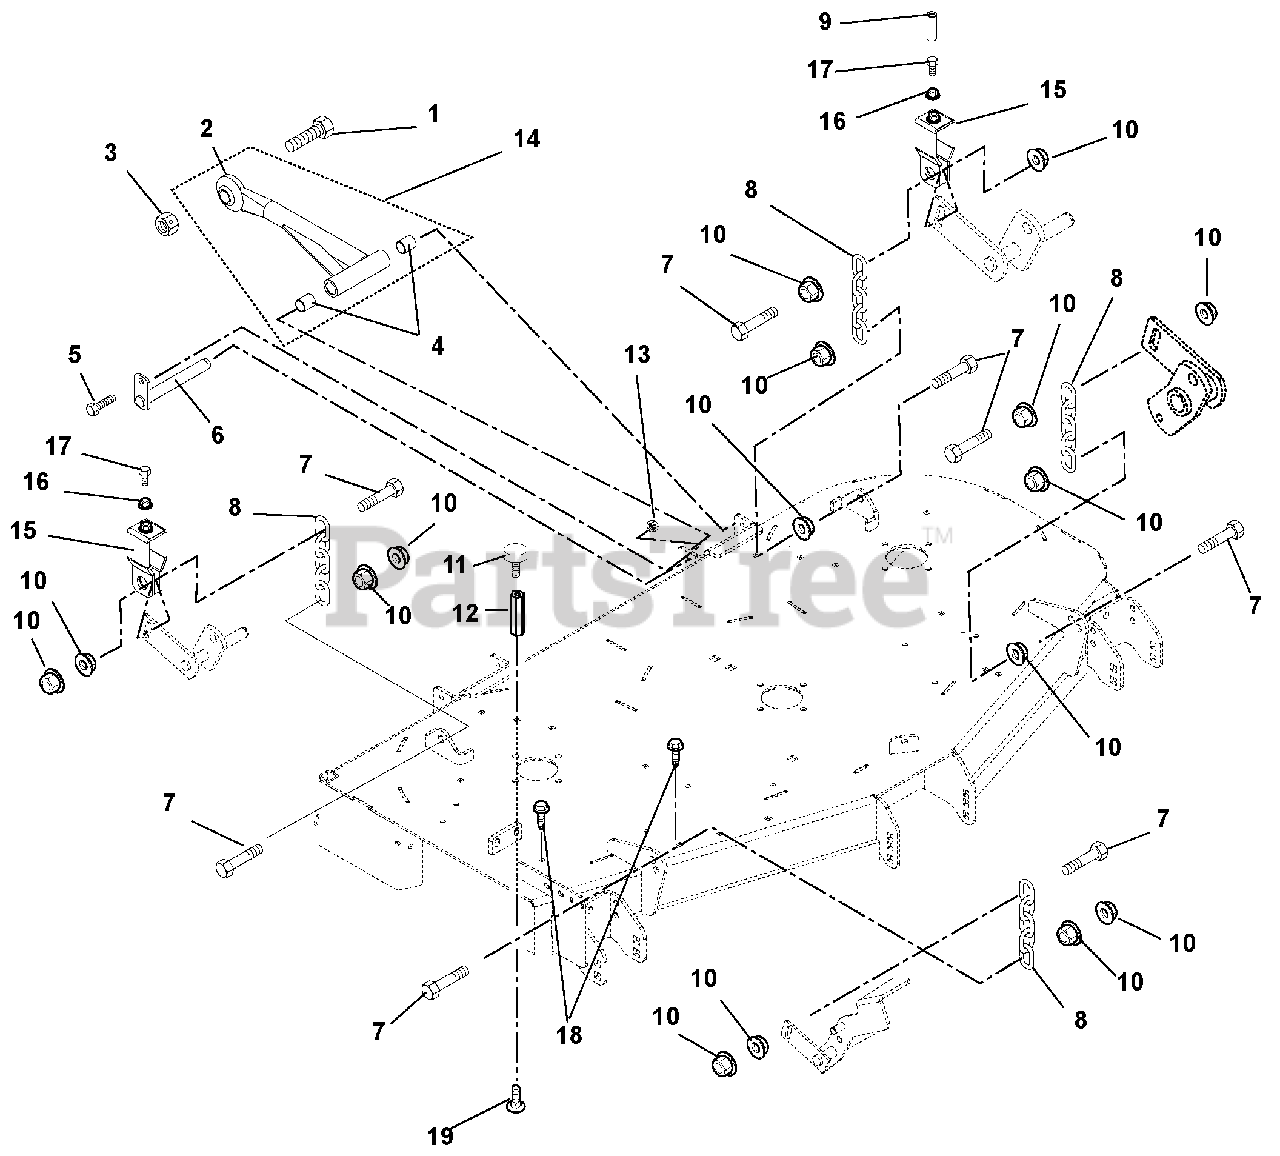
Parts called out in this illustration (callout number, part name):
1	Bolt, Hex .875-9 x 2.75 Grade 5
2	Mower Mounting Arm Weldment
3	Nut, Locking Center .875-9
4	Bearing, .75 x .875 x 1.00
5	Bolt, Hex .38-16 x 1.00 Grade 5
6	Weldment, Mower Mounting Pin
7	Bolt, Hex M12-1.75 x 50 Grade 5
8	Chain, Link
9	Cap, Vinyl .50 ID x 1.50LG x .055
10	Nut, Spin Lock Flange M12-1.75
11	Bumper, Rubber
12	Nut, Coupling .31-18 x 3.00
13	Nut, .38-16 Nyloc Flange
14	Assembly, Mower Mounting Arm (Includes item # 2 and item # 4)
15	Bracket, Deck Leveling
16	Nut, Jam .312-18
17	Bolt, Full Thread Hex .312-18 x 2.00
18	Screw, Tapping Hex Washer Head Thread .38-16 x .50
19	Bolt, Round Head Square Neck .31-18 x .75
